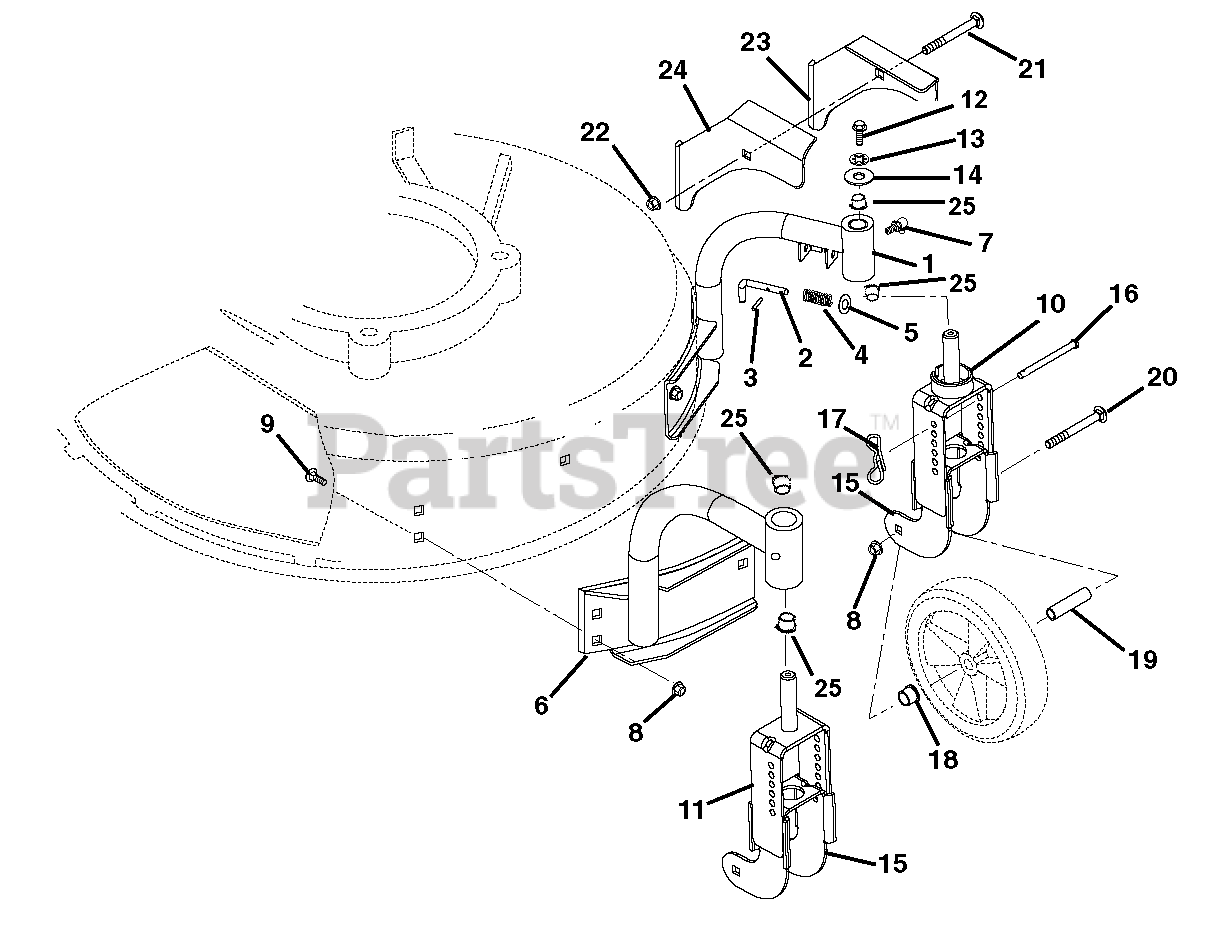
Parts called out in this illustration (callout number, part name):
1	Weldment, Left Hand Mount
2	Pin, Lockout
3	Pin, Roll .094 x .50
4	Spring, Compression - Swivel Lockout
5	Washer, Flat Steel .281 x .62 x .065
6	Weldment, Right Hand Mount
7	Fitting, Lube .25-28 x .256
8	Nut, Spin Lock Flange .312-18
9	Bolt, Round Head Square Neck .31-18 x .50 Grade 5
10	Yoke, Left Hand Outer
11	Yoke, Right Hand Outer
12	Bolt, Hex .25-20 x .75 Grade 5
13	Washer, Locking .25 x .062 Regular
14	Washer, Flat Steel .28 x 1.00 x .063
15	Yoke, Inner
16	Pin, Height Adjustment
17	Pin, Bow Tie Locking Cotter
18	Bushing, Flange .50 x .625 x .50 x .75
19	Spacer, Wheel
20	Bolt, Round Head Square Neck .31-18 x 2.75
21	Bolt, Round Head Square Neck .25-20 x 1.50 Grade 5
22	Nut, Locking Flange .25-20
23	Bracket, Hood Cable Left Hand
24	Bracket, Hood Cable Right Hand
25	Bushing, SLeeve .625 x .750 x .500 BR
